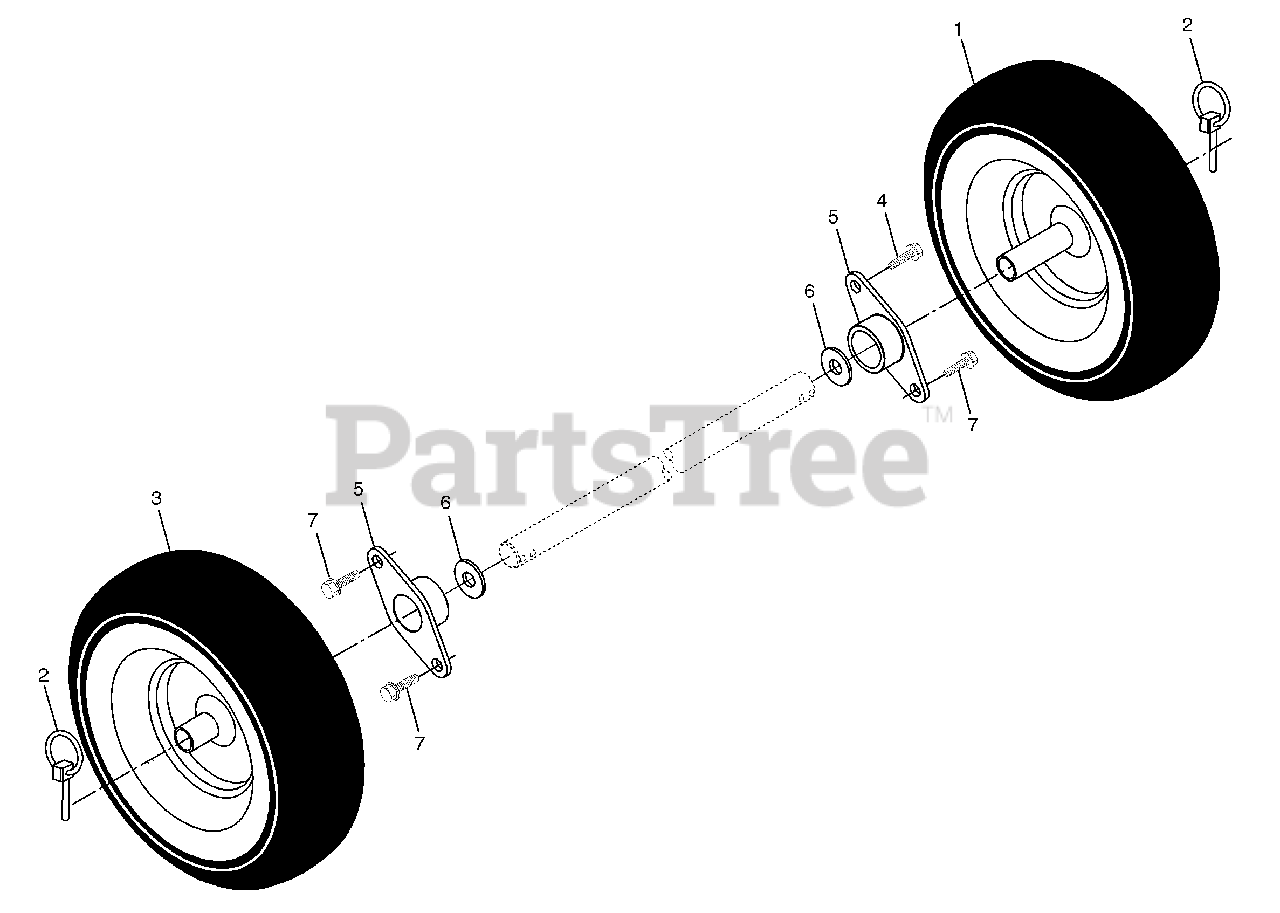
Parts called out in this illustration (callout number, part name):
1	Wheel Assembly, 16", LH
2	Pin, Klik 1/4
3	Wheel Assembly, 16", RH
4	Screw, Hex Head 5/16-18 x 5/8
5	Bearing, Axle
6	Washer, Thrust
7	Screw, Hex Head 5/16-18 x 3/4
